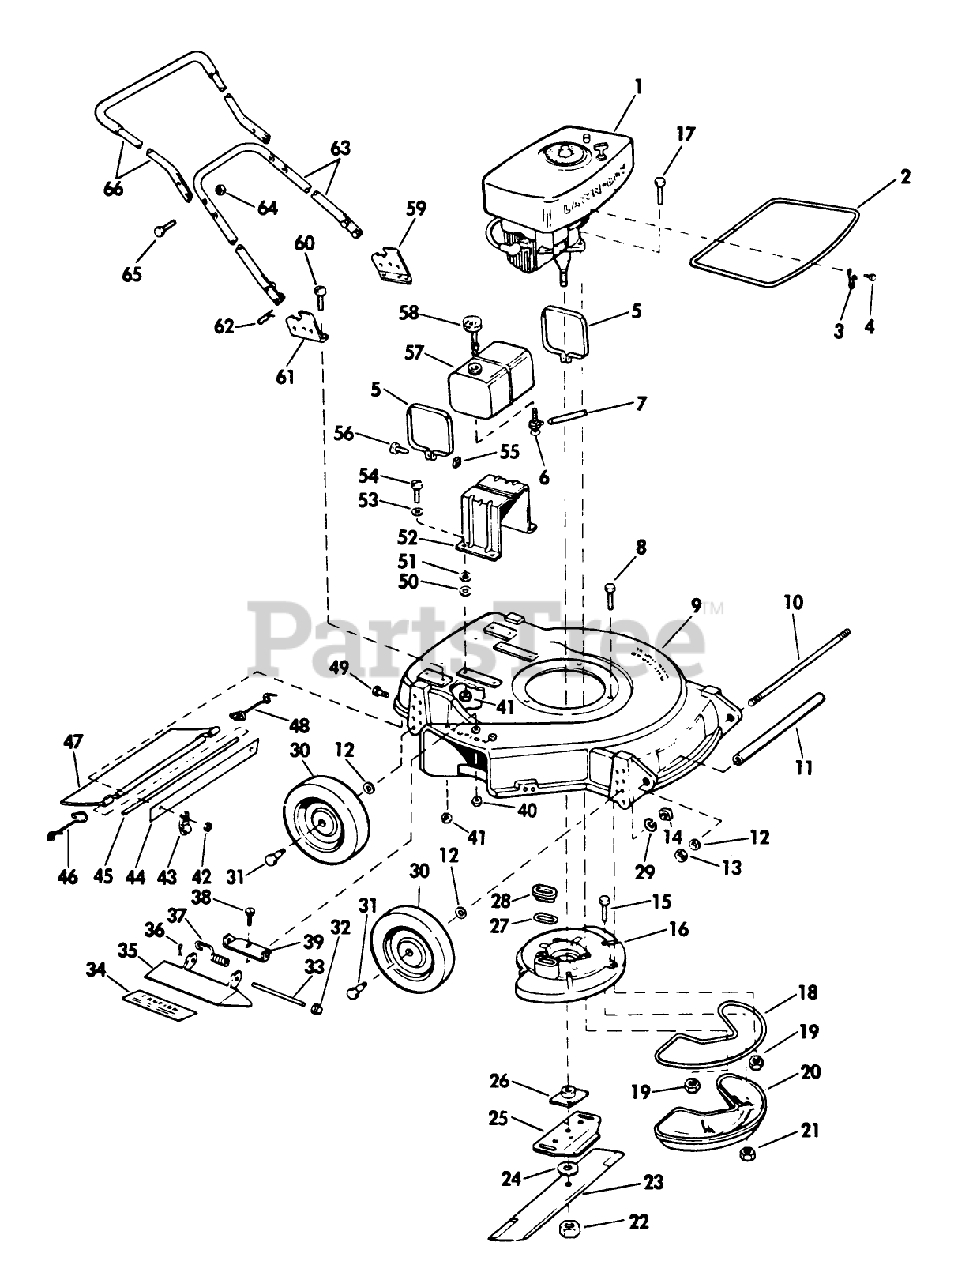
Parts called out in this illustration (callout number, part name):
1	See Note #2 at bottom of this page.
6	VALVE&SCREEN SM
12	WASHER WROUGHT
13	LOCKNUT
19	NUT-LOCK F
22	NUT-BLADE
26	PLATE AND COLLAR ASM
27	GASKET S
29	WASHER, LOCK
33	HINGE PIN
36	Cotter Pin
40	LOCKNUT E
41	LOCKNUT E
42	LOCKNUT E
46	SPRING;TRAILING SHIELD RH
48	SPRIG T/SHLD ASOC
54	BOLT PIONEER
60	SCREW S
64	LOCKNUT E
